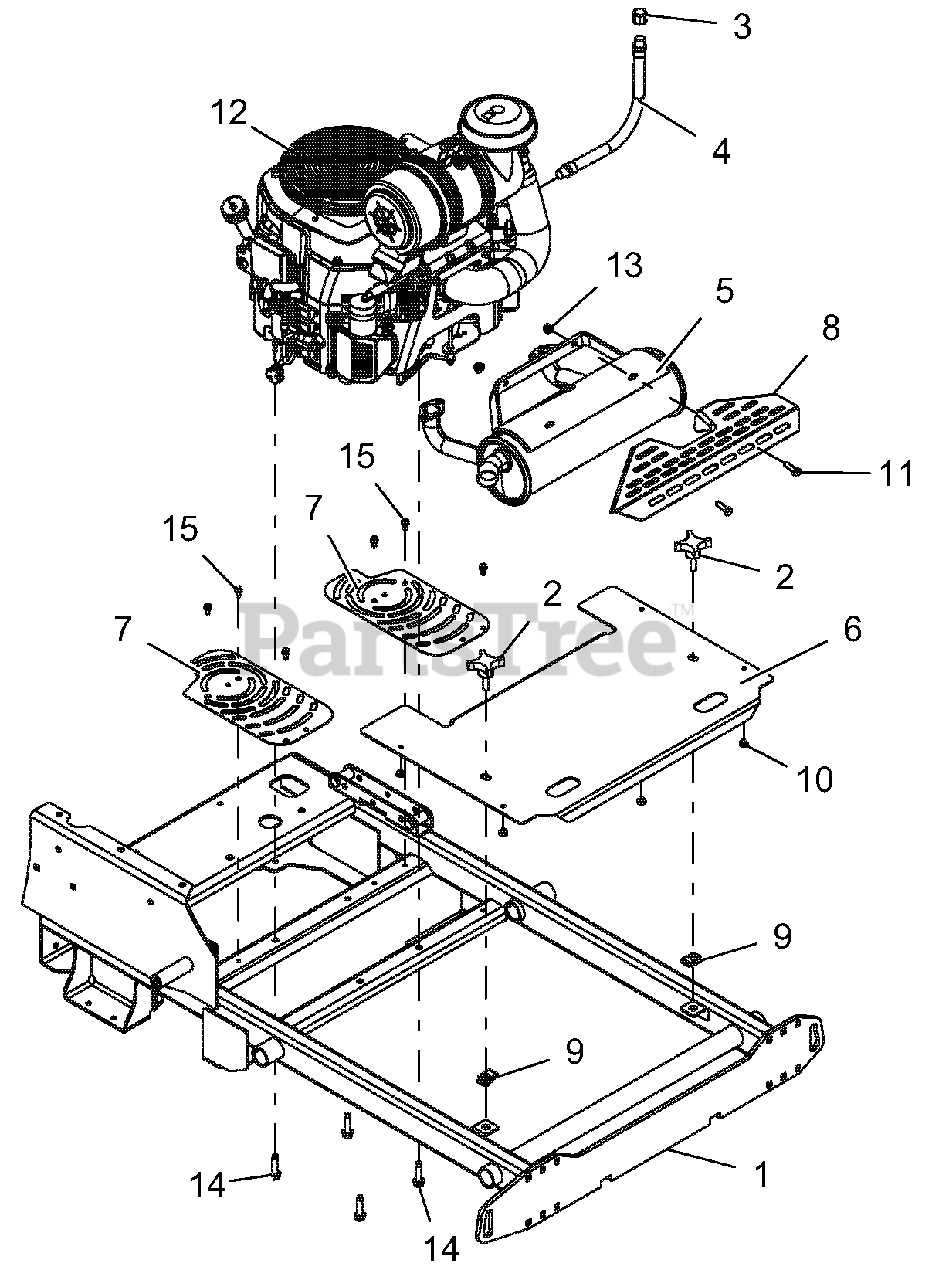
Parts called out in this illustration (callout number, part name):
1	WLDMT, FRAME PROSTANCE
2	KNOB, 3/8 X 1.25 - 4 PRONG
3	PIPE, CAP 3/8 NPT FEMALE
4	HOSE, HYD .38-11-OK M6N0-M6N0
5	MFLR, KOHLER
6	SHIELD, FRONT PRO-STANCE-RED
7	GUARD, FAN
8	GUARD, HEAT SHIELD (BLACK)
9	NUT, RTNR .375-16X.37
10	BUMPER GROMMET .125 X .25 REV
11	BLT-HEX .31-18X1.00 GR5 YWZC
12	ENGINE, KOHLER EFI ECV730
13	NUT-LK-NYL-FLG .31-18 YWZC
14	SCR-TAP .38-16X1.50 HWH TR YZ
15	SCR-TAP .25-20X.50 HWH TR YWZ
